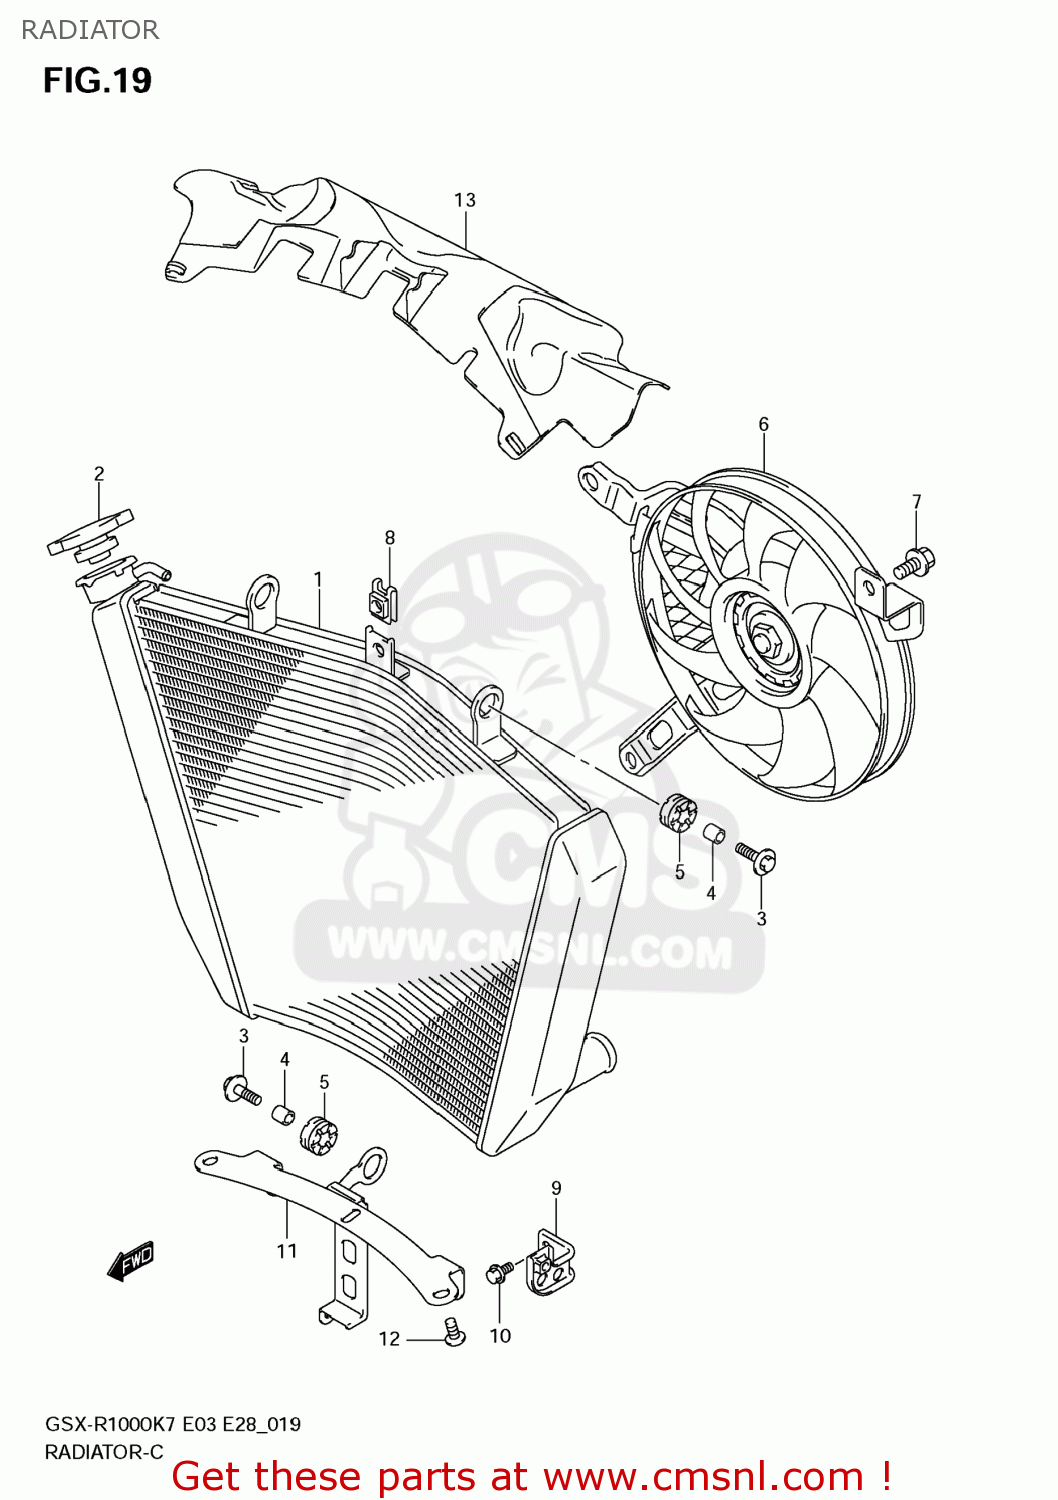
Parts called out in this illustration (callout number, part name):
1	RADIATOR ASSY,WATER
2	CAP COMP,RADIATOR
3	BOLT(6X25)
4	SPACER(6.5X10X12)
5	CUSHION
6	FAN ASSY,RADIATOR
7	BOLT,FAN ASSY
8	NUT,FAN ASSY
9	BRACKET,RDTR & OIL COOLER
10	BOLT
11	BRACKET,RADIATOR SUPPORT
12	BOLT
13	SHIELD,RADIATOR HEAT
